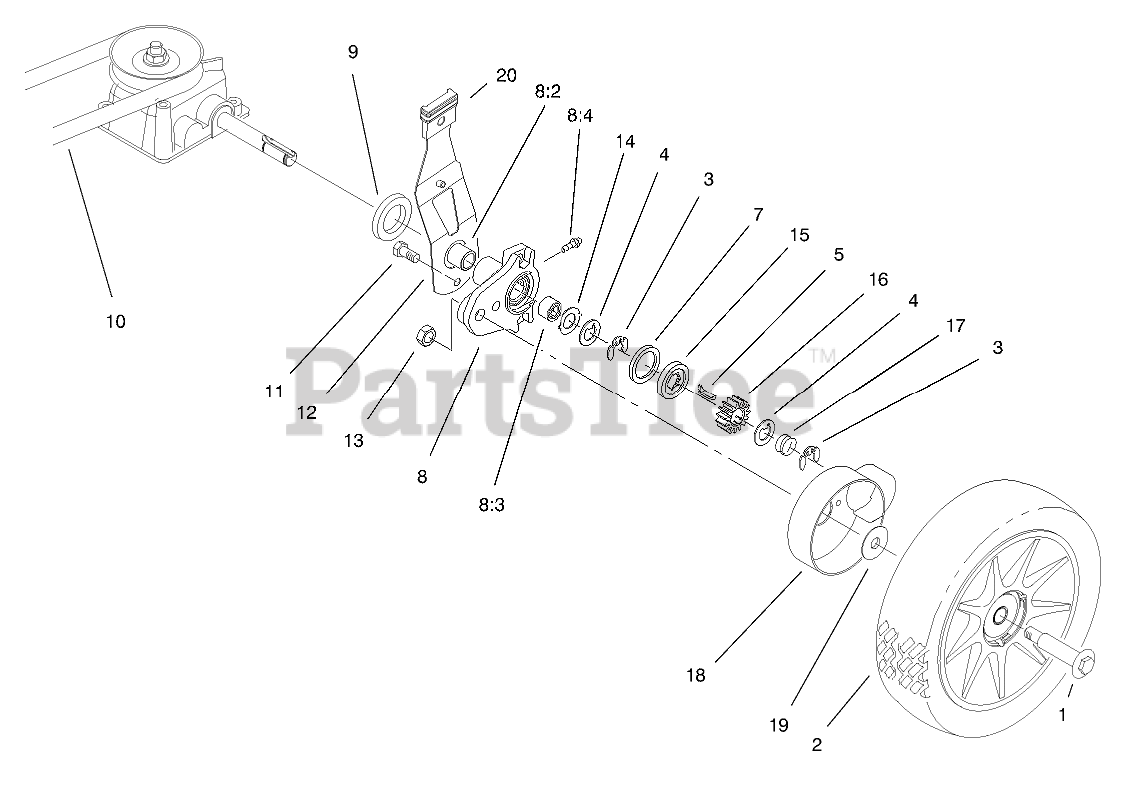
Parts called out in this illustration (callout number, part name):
1	BOLT-SHOULDER
2	WHEEL AND TIRE ASM
3	RING-CLIP, LOCKING
4	WASHER-THRUST, KEYED
5	KEY-ROCKING, LH
6	KEY-ROCKING, RH
7	RING-FRICTION
8	REAR HEIGHT ADJUSTMENT ARM ASM
8:2	BUSHING
8:3	BUSHING
8:4	FITTING-GREASE
9	SPACER-AXLE SHAFT
10	V-BELT
11	SCREW-HWH
12	REAR SPRING ARM ASM
13	NUT-JAM, LOCKING
14	WASHER-ARM, PIVOT
15	WASHER-CLUTCH
16	GEAR-PINION
17	SPRING-COMPRESSION
18	COVER-WHEEL
19	WASHER-STEPPED
20	KNOB-LEVER, HEIGHT ADJUSTMENT
